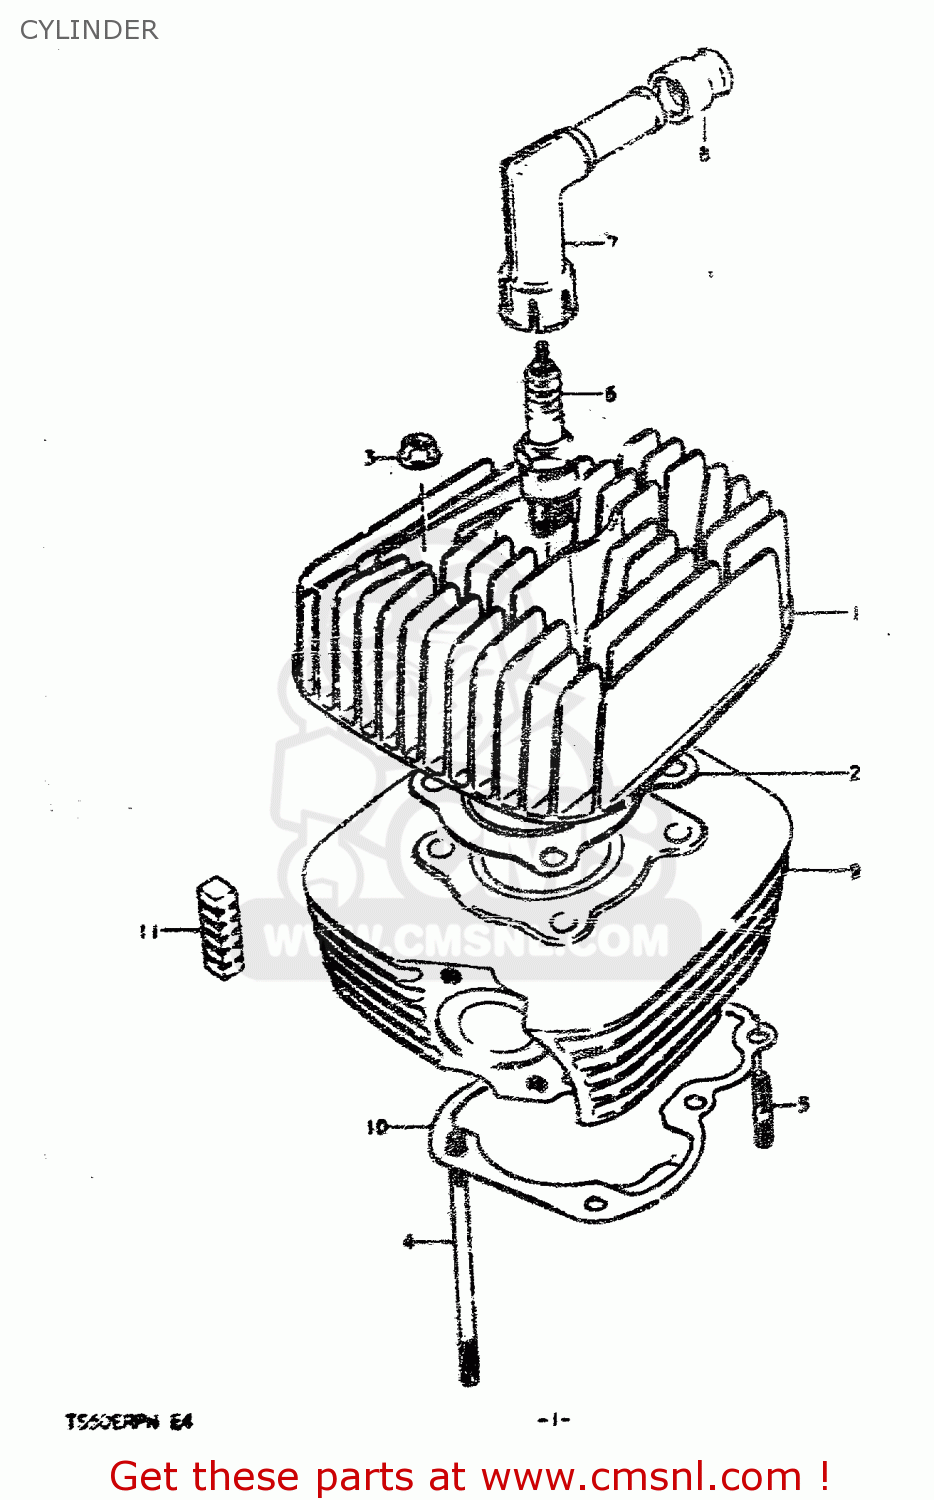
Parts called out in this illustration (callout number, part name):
1	CYLINDER HEAD
2	GASKET
3	NUT
4	BOLT
5	STUD 6X16
6	SPARK PLUG (ND,W20EP)
7	CAP, SPARK PLUG
8	SEAL, SPARK PLUG
9	CYLINDER
10	GASKET,CYLINDER (MCA)
11	PAD,CYLINDER
